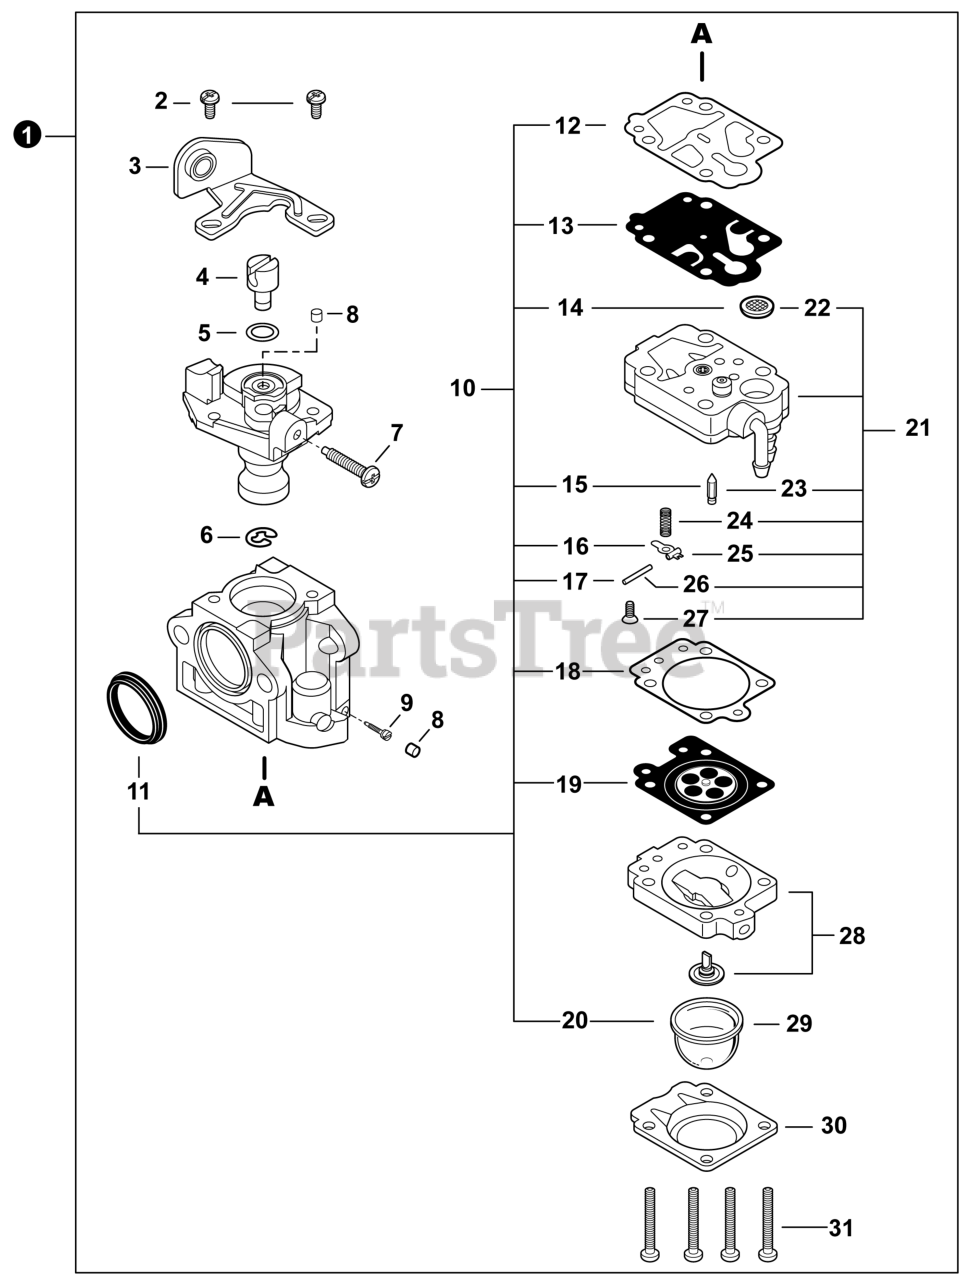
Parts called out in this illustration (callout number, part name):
1	CARBURETOR - WYK-192A
3	BRACKET, THROTTLE CABLE
9	NEEDLE, HIGH SPEED
10	REPAIR KIT, CARBURETOR
11	RING, PACKING
12	GASKET, PUMP
13	DIAPHRAGM, FUEL PUMP
14	SCREEN, FUEL INLET
15	VALVE, INLET NEEDLE
16	LEVER, METERING
17	PIN, METERING LEVER
18	GASKET, METERING DIAPHRAGM
19	DIAPHRAGM, METERING
20	BULB, PURGE
21	BODY ASSY, PUMP
22	SCREEN, FUEL INLET
23	VALVE, INLET NEEDLE
24	SPRING, METERING LEVER
25	LEVER, METERING
26	PIN, METERING LEVER
27	SCREW
28	BODY ASSY, PURGE
29	BULB, PURGE
30	RETAINER, PURGE BULB
